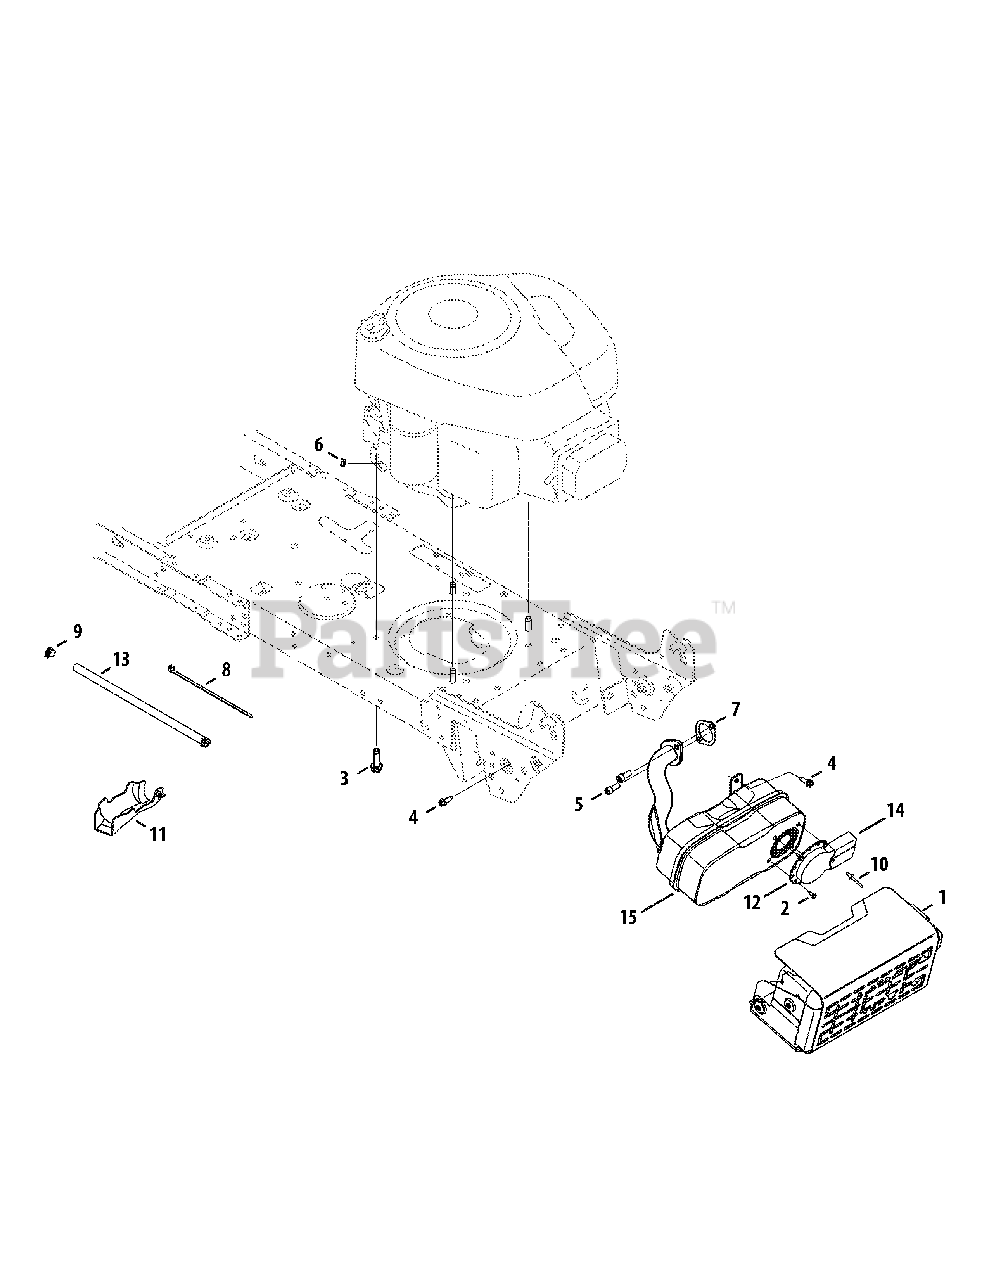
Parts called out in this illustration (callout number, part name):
1	Muffler Shield Assembly
2	Screw, AB #8-18 0.500
3	Tap Screw, 3/8-16 1.000
4	Tap Screw, 1/4-20 0.750
5	Screw, Socket Head, 5/16-18 x .750
6	Sems Nut, 1/4-20
7	Exhaust Gasket
8	Cable Tie, 3/16 X .05 X 7.4
9	Hose Clamp, .490 Dia.
10	Pop Rivet, .188 Dia X .300 L
11	Oil Drain Sleeve
12	Muffler Deflector
13	Low Permeation Fuel Hose, 1/4
14	Long Muffler Deflector
15	Briggs Single Muffler
